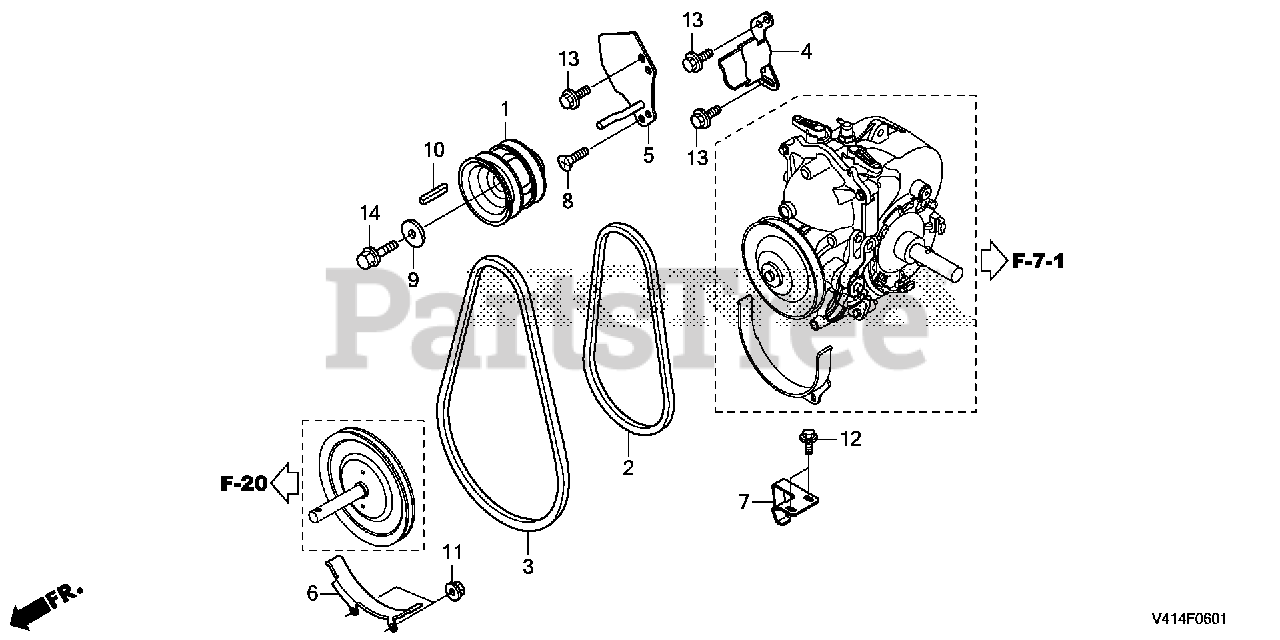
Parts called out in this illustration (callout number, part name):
1	PULLEY, DRIVE
2	V-BELT (SA-37) (W400)
3	V-BELT (SB-41.5) (W800)
4	STOPPER, L. BELT
5	STOPPER, R. BELT
6	STOPPER, AUGER BELT
7	GUIDE, BELT
8	BOLT, LOCK STRIKER
9	WASHER, LOCK (8MM)
10	KEY (7X7X33)
11	NUT, FLANGE (6MM)
12	BOLT, FLANGE (6X14)
13	BOLT, FLANGE (8X16) Use from Engine SN 1000016.
14	BOLT, FLANGE (8X28)
